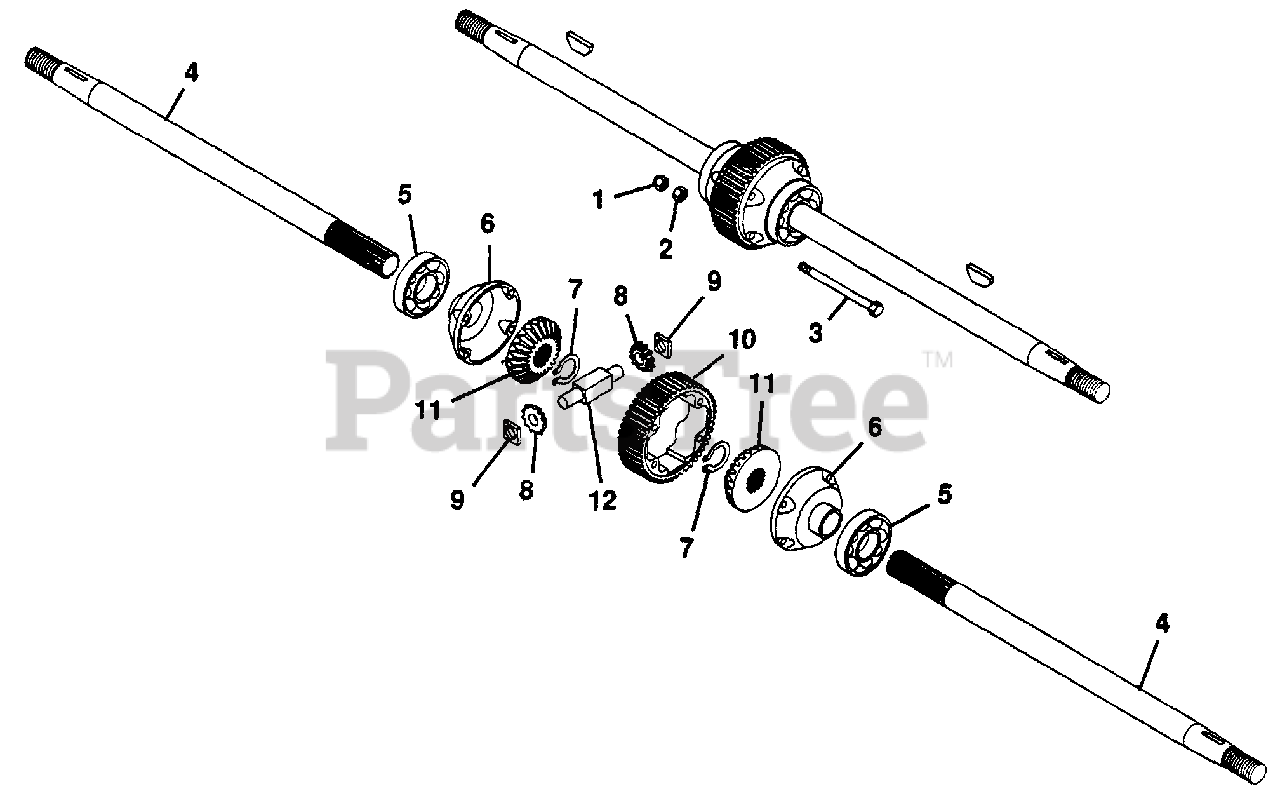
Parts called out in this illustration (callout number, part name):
1	Nut, Lock 5/16-18
2	Nut, Hex 5/16-18 Grade-8
3	Bolt, Hex 5/16-18x2.75 Grade-8
4	Axle,
5	Bearing, Ball
6	Cap, Differential End
7	Ring, Retaining 1.250 Shaft Heavy
8	Pinion, Bevel
9	Block, Drive
10	Gear, Final Drive
11	Gear, Bevel
12	Pin, Spider Pinion
